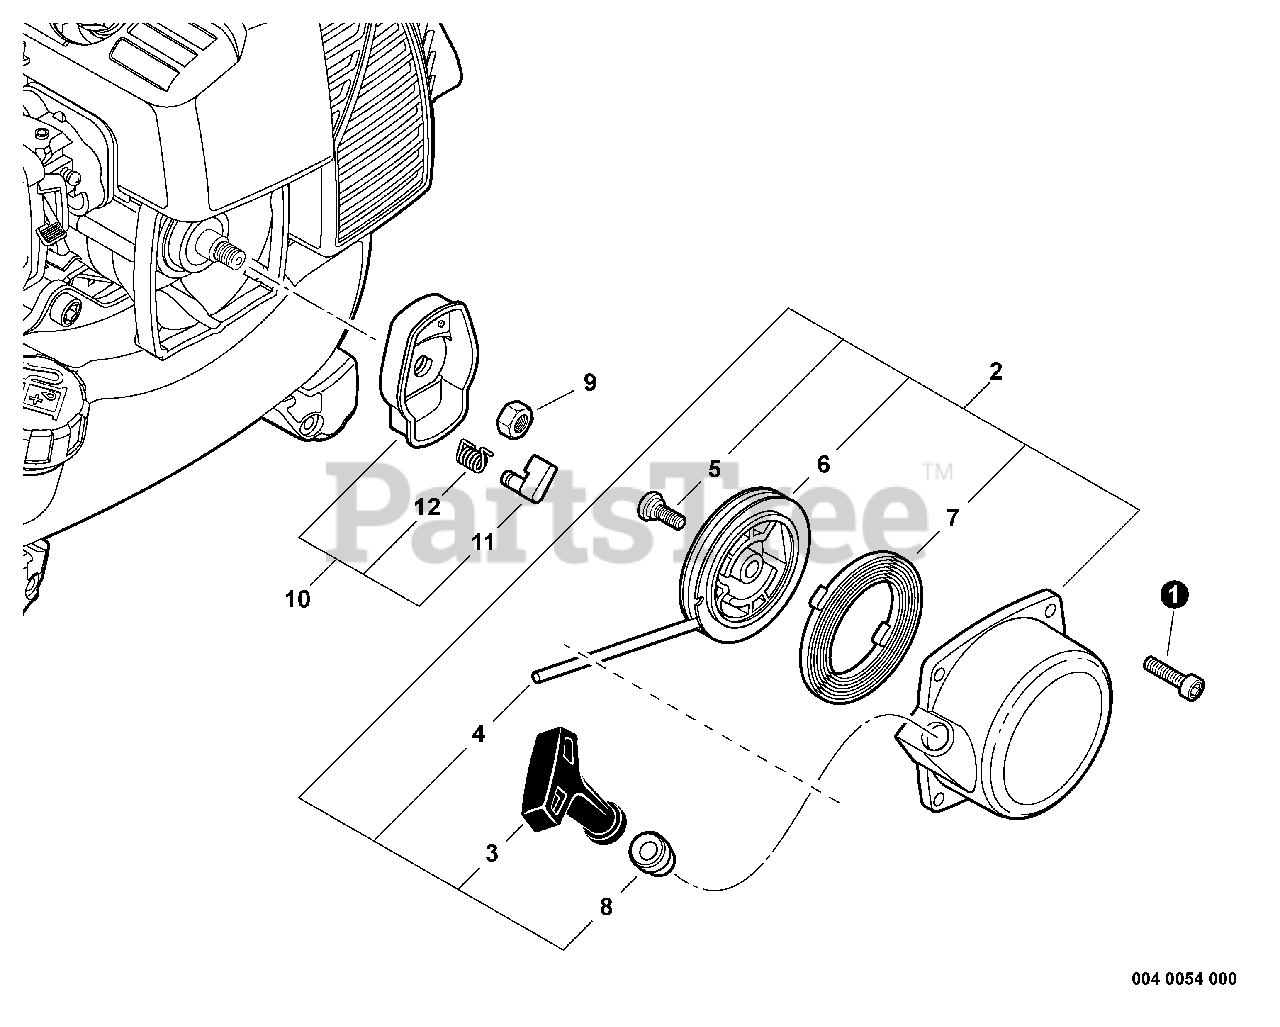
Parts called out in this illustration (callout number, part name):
1	SCREW - 4X16
2	STARTER ASSY
3	GRIP, STARTER
4	ROPE, STARTER - 3X1000
6	REEL, ROPE
7	SPRING, REWIND
8	GUIDE, ROPE
10	STARTER PAWL ASSY
11	PAWL, STARTER - BLACK
12	SPRING, RETURN
